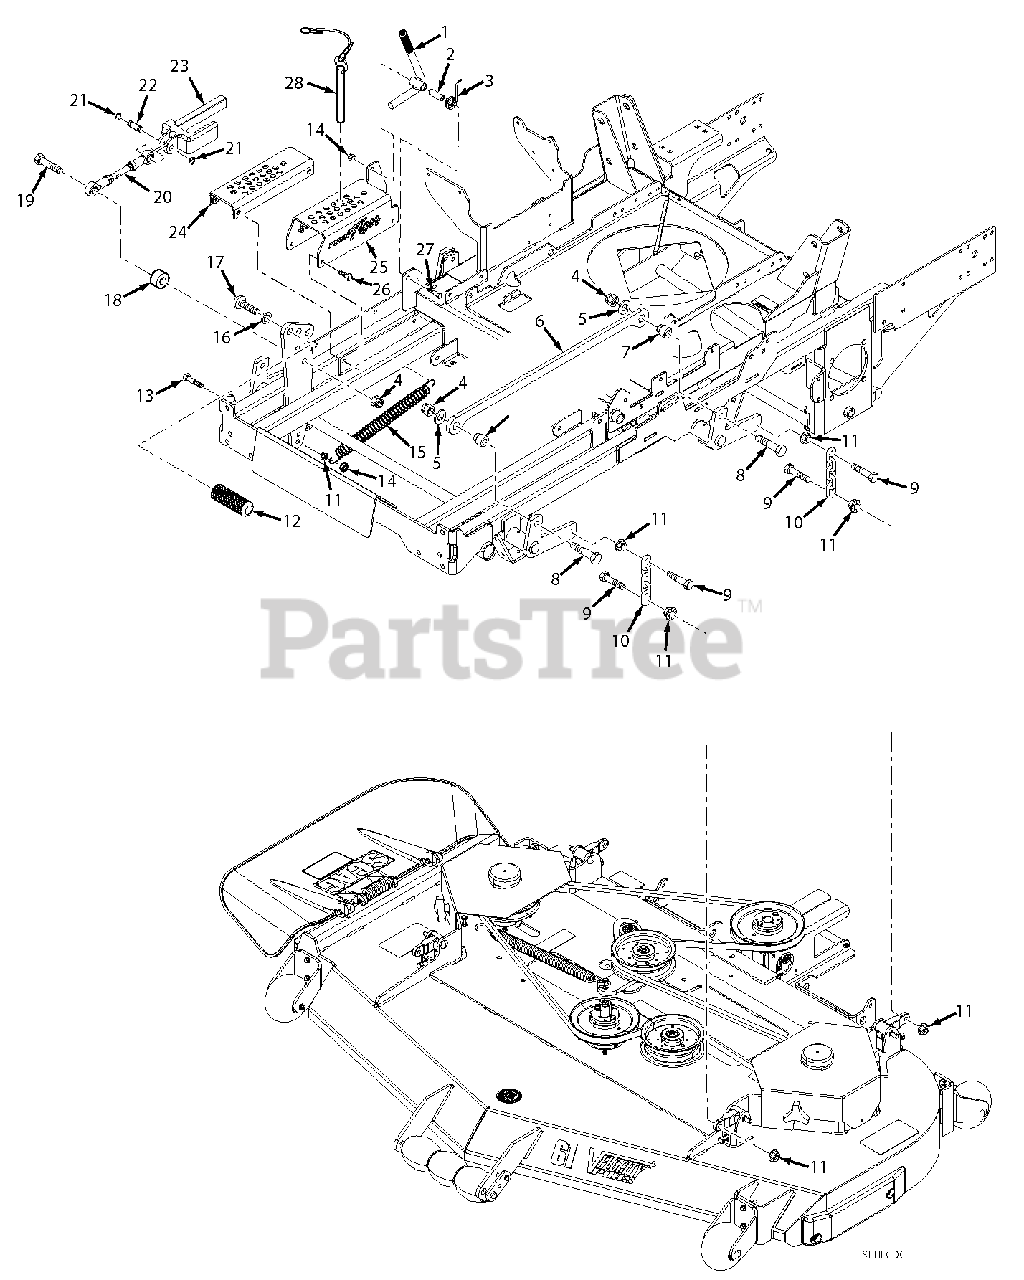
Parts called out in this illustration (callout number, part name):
1	Deck Latch Weldment w/Grip
2	Spacer, Deck Latch
3	Spring, Torsion Lever Return
4	Nut, Elastic Stop 1/2-13
5	Flatwasher, 1/2-.562 x 1.375 x .109
6	Link, Deck Lift
7	Pivot, Deck Link
8	Bolt, Hex Head 1/2-13 x 2-1/4"
9	Bolt, Hex Head 3/8-16 x 1-1/2"
10	Chain
11	Nut, Serrated Flange 3/8-16
12	Pedal, Foot
13	Bolt, Hex Head 3/8-16 x 1-1/2"
14	Nut, Center Lock 3/8-16
15	Spring, Ext. Deck Lift
16	Lockwasher, 5/8"
17	Capscrew, 5/8-11 x 1-1/2"
18	Spacer
19	Bolt, Hex Head 1/2-13 x 2"
20	Linkage, Deck Lift
21	Retaining Ring, 1/2" Ext. "E"
22	Pin, Deck Lift
23	Slide, Height Adjust
24	Weldment, Lower Cutting Height
25	Adjustment Bracket, Cutting Height Upper
26	Bolt, Hex Head 5/16-18 x 1-1/4"
27	Bolt, Hex Head 3/8-16 x 2-1/4"
28	Ring Pin Assy., w/Lanyard
